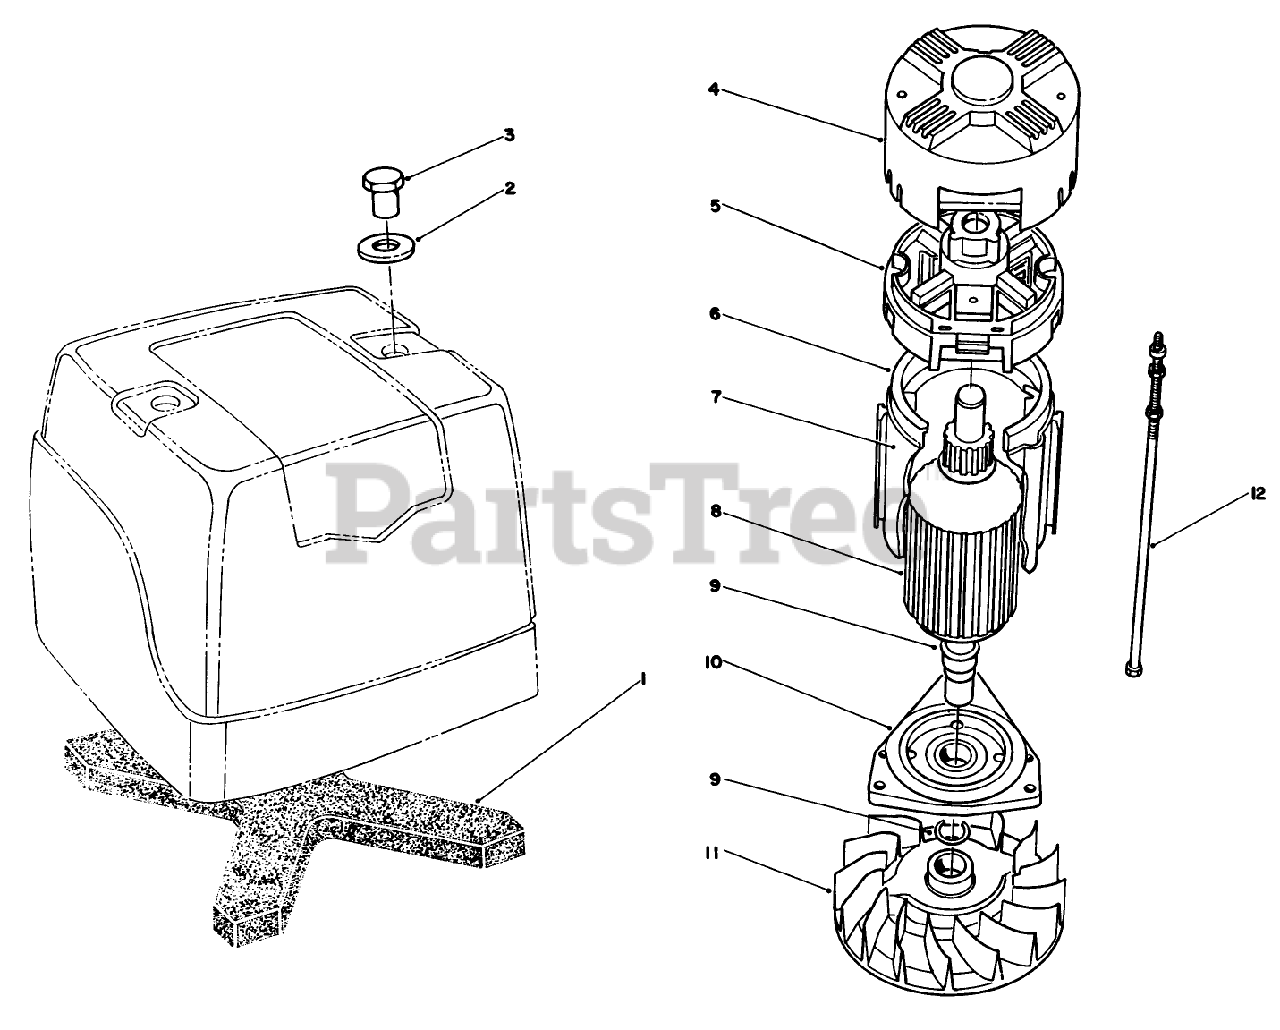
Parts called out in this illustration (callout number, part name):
1	Filter
2	Washer
3	Nut-Hex
4	End Cap-Brush
5	Brush Box Group (Includes: 490834 Brush Pin Group)
6	Housing Assembly
7	Insulator Group-Housing
8	Armature Group
9	Ring-Retaining
10	Spacer
12	Washer-Lock
